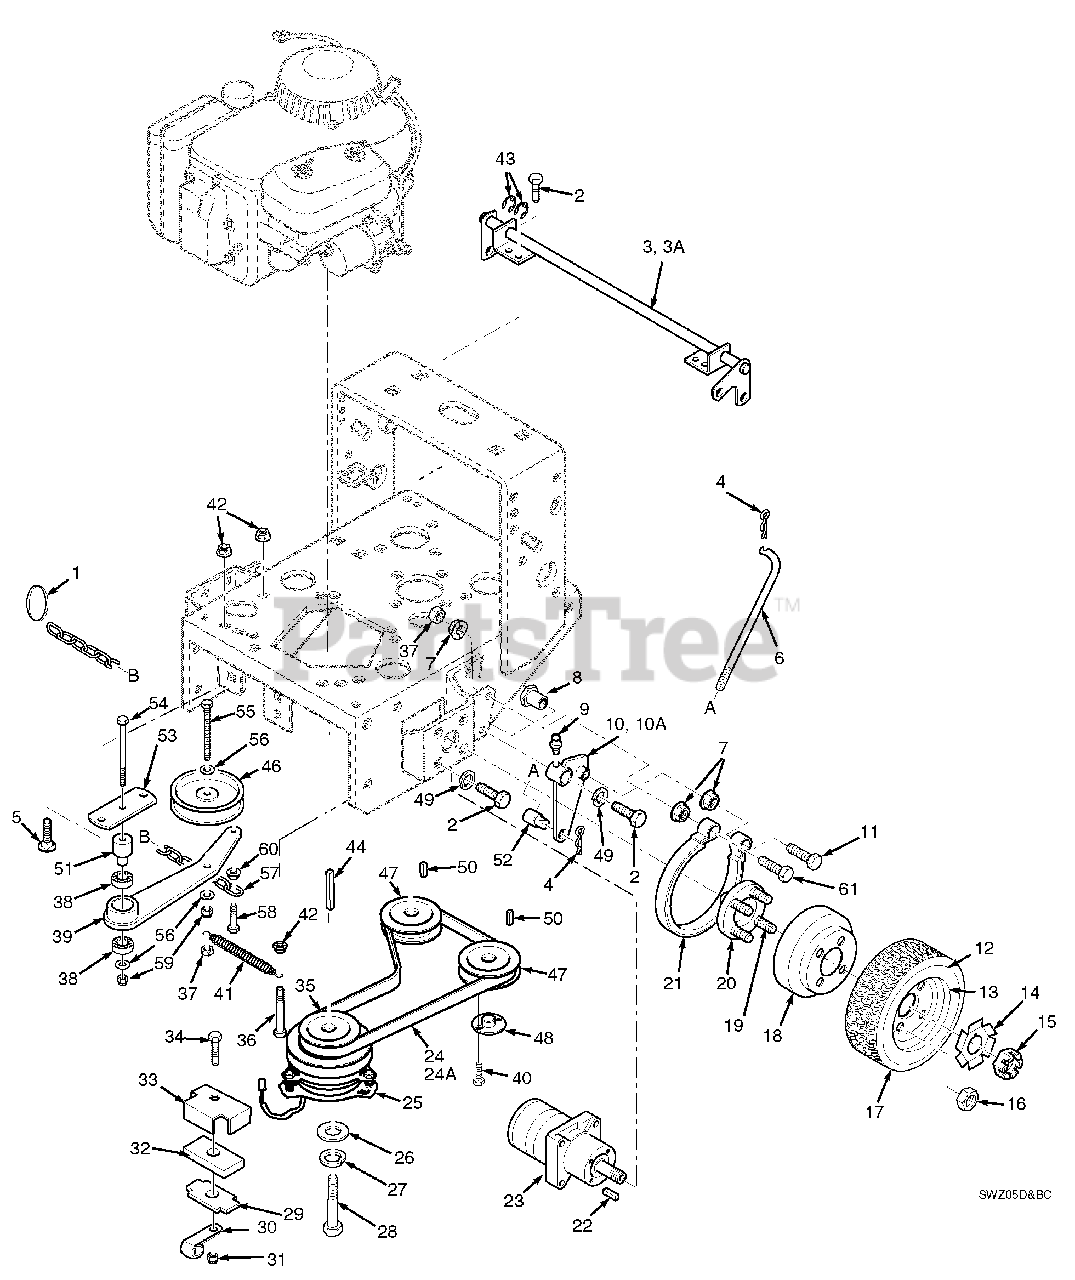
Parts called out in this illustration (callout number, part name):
1	Ring, Split
2	Bolt, 3/8-16 x 1" Hex Head
3	Brake Shaft Assembly Weldment, 16" Small Frame
3A	Brake Shaft Assembly Weldment, 20" Large Frame
4	Hair Pin Cotter, .094 x 1.62
5	Carrage Bolt, 5/16-18 x .75"
6	Rod, Brake Lower
7	Nut, 3/8-16 Serr. Flange
8	Bushing, Brake
9	Grease Fitting
10	Brake Actuator Weldment-LH
10A	Brake Actuator Weldment-RH
11	Bolt, 3/8-16 x 2-1/4"
12	Tire, 16 x 6.50, 4 ply
13	Rim Assy
14	Lock Washer, Wheel Motor
15	Hex Castle Nut, 3/4-28 UNEF
16	Nut, Lug
17	Wheel Assy.,
18	Brake Drum
19	1/2-20 Serrated Bolt
20	Hub, Wheel
21	Brake Band, 7.5"
22	Key, 3/16 X .75 Woodruff
23	Wheel Motor
24	Belt, Pump Drive, 16" Small Frame
24A	Belt, Pump Drive, 20" Large Frame
25	Electric Clutch
26	Flat Washer .469 x 1.75 x .25
27	Lock Washer, 7/16"
28	Hex Head Bolt, 7/16-20 x 2-3/4"
29	Plate, Backing
31	Nut, 5/16-18 Elastic Stop
32	Rubber Pad, Clutch Stop
33	Retainer, Clutch Stop
34	Hex Head Bolt, 5/16-18 x 1.75"
35	Pulley, Pump Drive Engine
36	Hex Head Bolt, 5/16-18 x 2.75"
37	Nut, 3/8-16 Center Lock
38	Ball Bearings
39	Idler Arm Weldment, Pump
40	Bolt, Hex Head 1/4-20 x 1" Grd 8
41	Spring, Pump Belt Idler
42	Nut, 5/16-18 Serr. Flange
43	Retaining Ring, 3/4" Ext. "E"
44	Key, 1/4x1/4 x 3.75"
45	Flat Washer, 3/8"
46	Pulley, Idler 4.5"
47	Pulley, Pump Shaft
48	Tapered Hub
49	Lockwasher, 3/8"
50	Key, 5.0 x 5.0 x 25mm
51	Pivot, Idler (Long)
52	Swivel Joint
53	Base, Idler Pivot
54	Bolt, Hex Head 3/8-16 x 3"
55	Bolt, Hex Head 3/8-16 x 2.75"
56	Flatwasher 3/8"
57	Chain
58	Bolt, Hex Head 1/4-20 x 1.25"
59	Nut, Hex Elastic Stop 3/8-16
60	Nut, Serrated Flange 1/4-20
61	Bolt, Hex Head 3/8-16 x 2.63"
